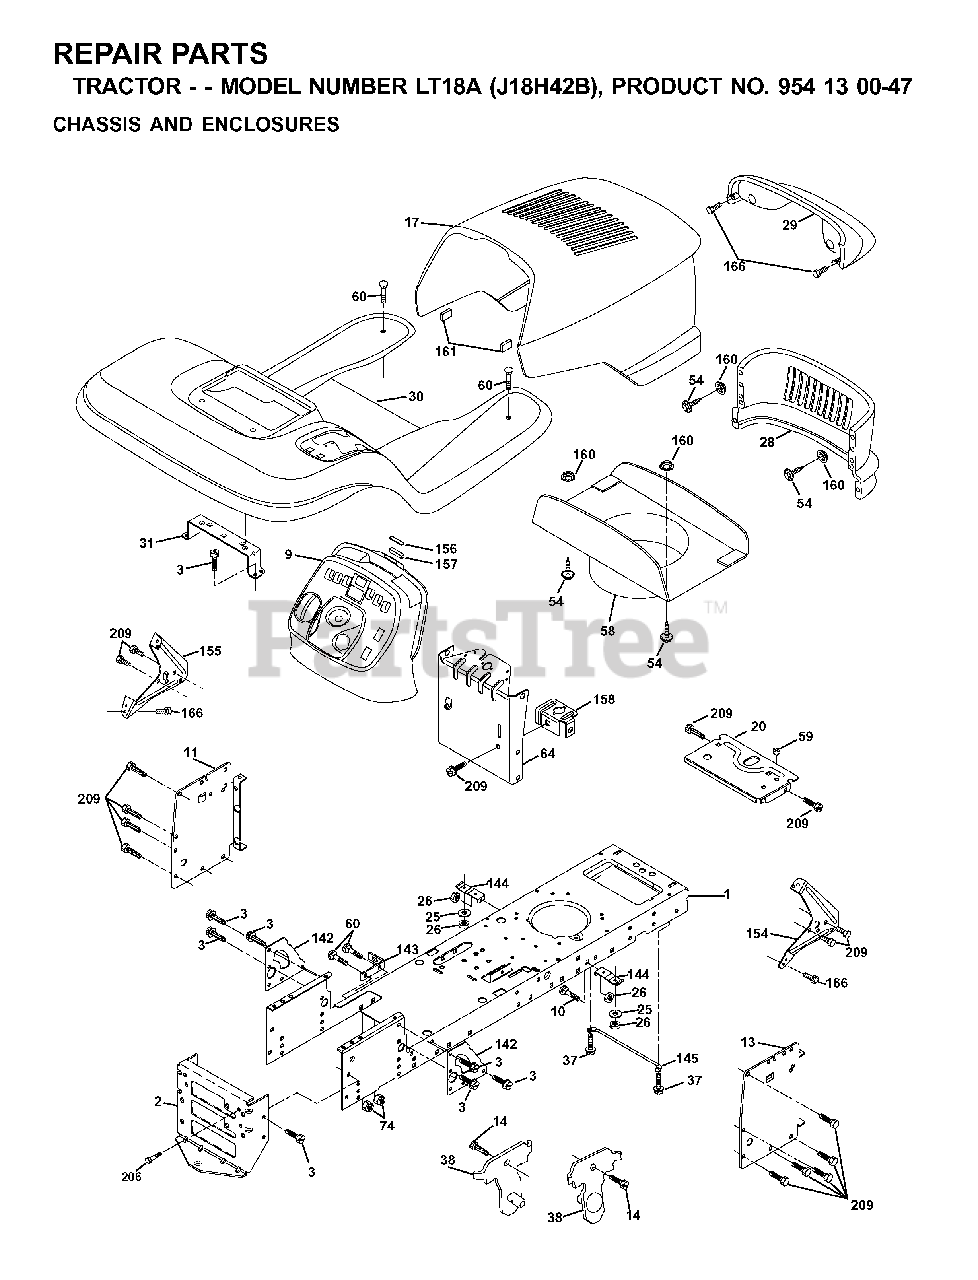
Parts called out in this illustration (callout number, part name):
1	CHASSIS STAMPING
2	DRAWBAR, 12GA
3	SCREW 3/8-16X3/4
10	BOLT D
25	WASHER
26	NUT
38	BRACKET
59	SNAP BUSHING T
74	LOCKNUT
142	PLATE
143	BRACKET, SWAY BAR
144	BRACKET FOOTREST
145	ROD PIVOT CHASSIS/HOOD
161	EXTRUSION BUMPER
166	SCREW
206	SHOULDER BOLT 5/16-18TT
209	SCREW, 3/8-16X3/4
